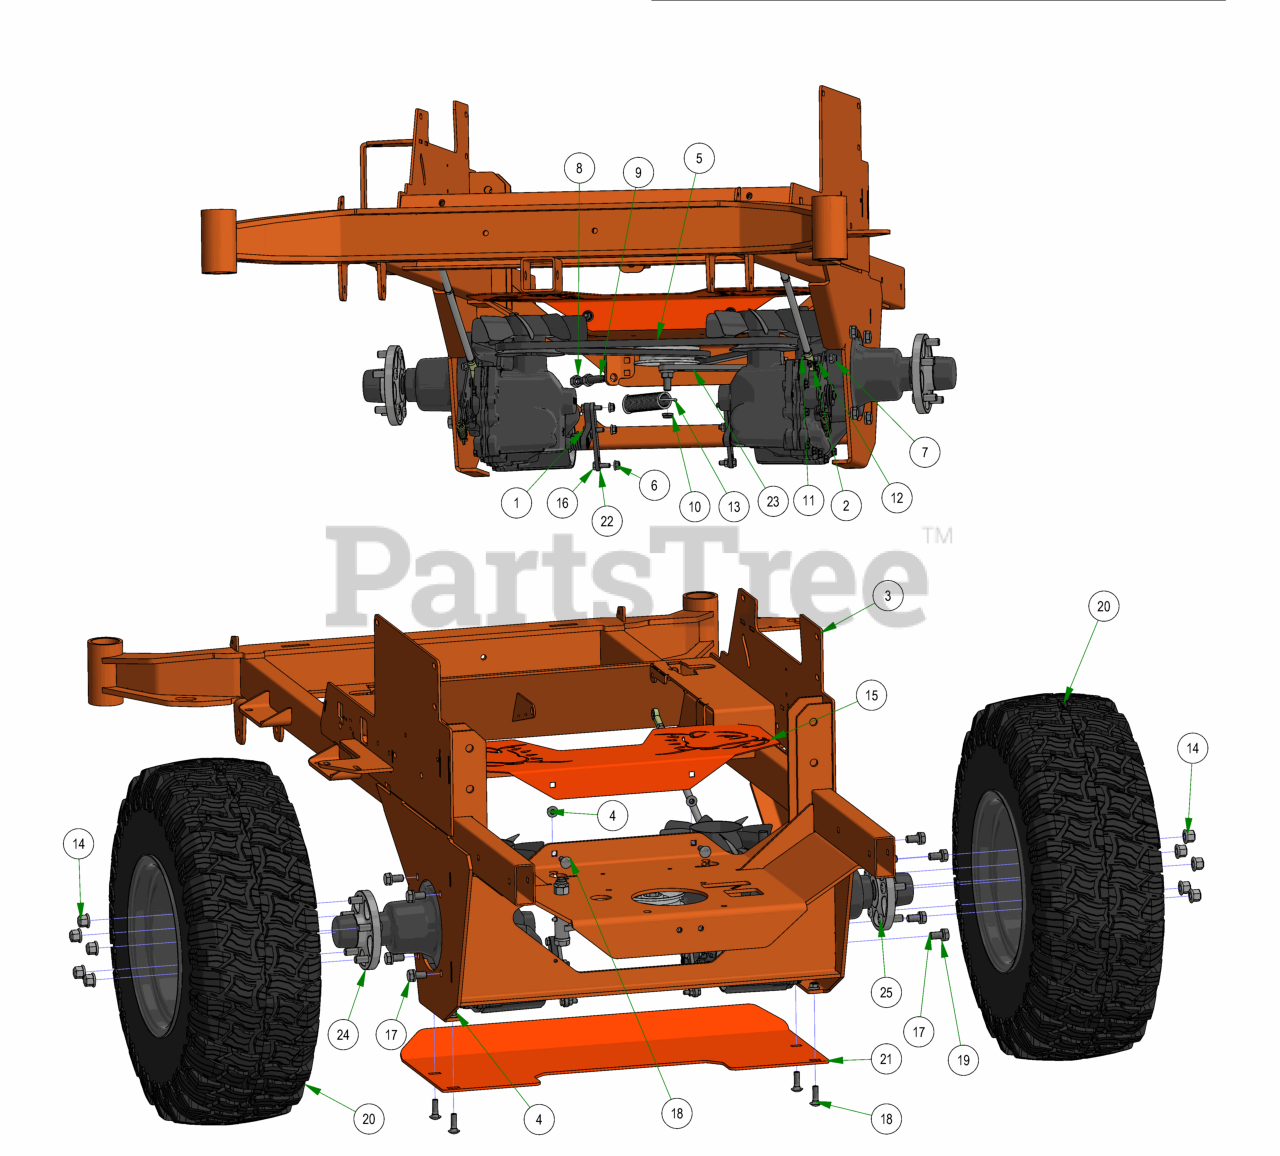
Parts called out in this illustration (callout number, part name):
1	5/16-18 X 1-1/4 HEX C/S (GR.5) ZC
2	2024 Rebel Push Rod Assembly
3	2023 Rebel Frame - Painted
4	3/8-16 NYLON INSERT FLANGE LOCKNUT (GR.F) ZINC
5	2019 Rebel Pump Belt
6	5/16-18 NYLON INSERT FLANGE LOCKNUT ZINC
7	3/8-16 NYLON INSERT LOCKNUT ZINC
8	1/2-13 HEX NUT ZINC
9	All Thread
10	1/2-13 NYLON INSERT JAM LOCKNUT ZINC
11	3/8-16 X 1-1/4 HEX CAP SCREW (GR.5) ZINC
12	Drive Arm Transaxle Spacer
13	Deck spring big diameter
14	Acorn Lug Nut
15	2019 Rigid Fan Guard
16	5/16-18 X 1 HEX CAP SCREW (GR.5) ZINC
17	1/2-13 X 1 HEX CAP SCREW (GR.5) ZINC
18	3/8-16 X 1-1/4 CARRIAGE BOLT ZINC
19	1/2 SPLIT LOCKWASHER (GR.8) ZINC/YELLOW
20	24x12-12 Reaper Turf Tire & Wheel Assembly
21	2019 Outlaw Rigid Skid Plate
22	2015 Outlaw Brake Adapter (4400 Transaxles Only)
23	2019 Rebel Pump Idler
24	4400 Transaxle-Left-Base Outlaw/2019 Rebel
25	4400 Transaxle-Right-Base Outlaw/2019 Rebel
